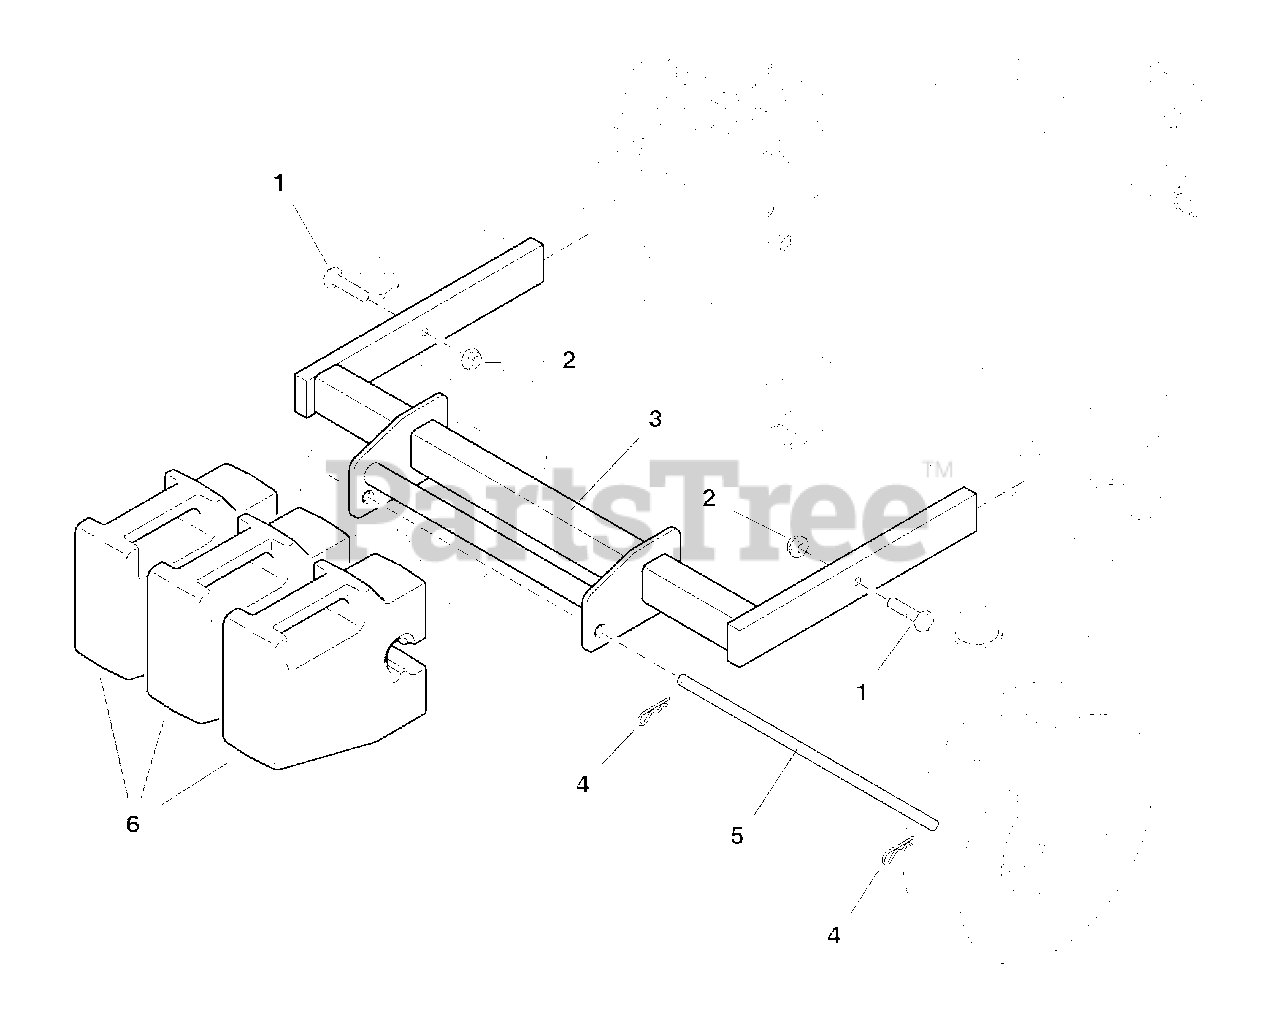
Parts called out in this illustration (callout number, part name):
1	CAPSCREW, Hex Hd, 3/8-16 x 2
2	NUT, Hex Nylon Lock, 3/8-16
3	WEIGHT MOUNT FRAME
4	HAIR PIN CLIP
5	RETAINING ROD
6	COUNTERWEIGHT, 50lbs (3-Bag Systems)
